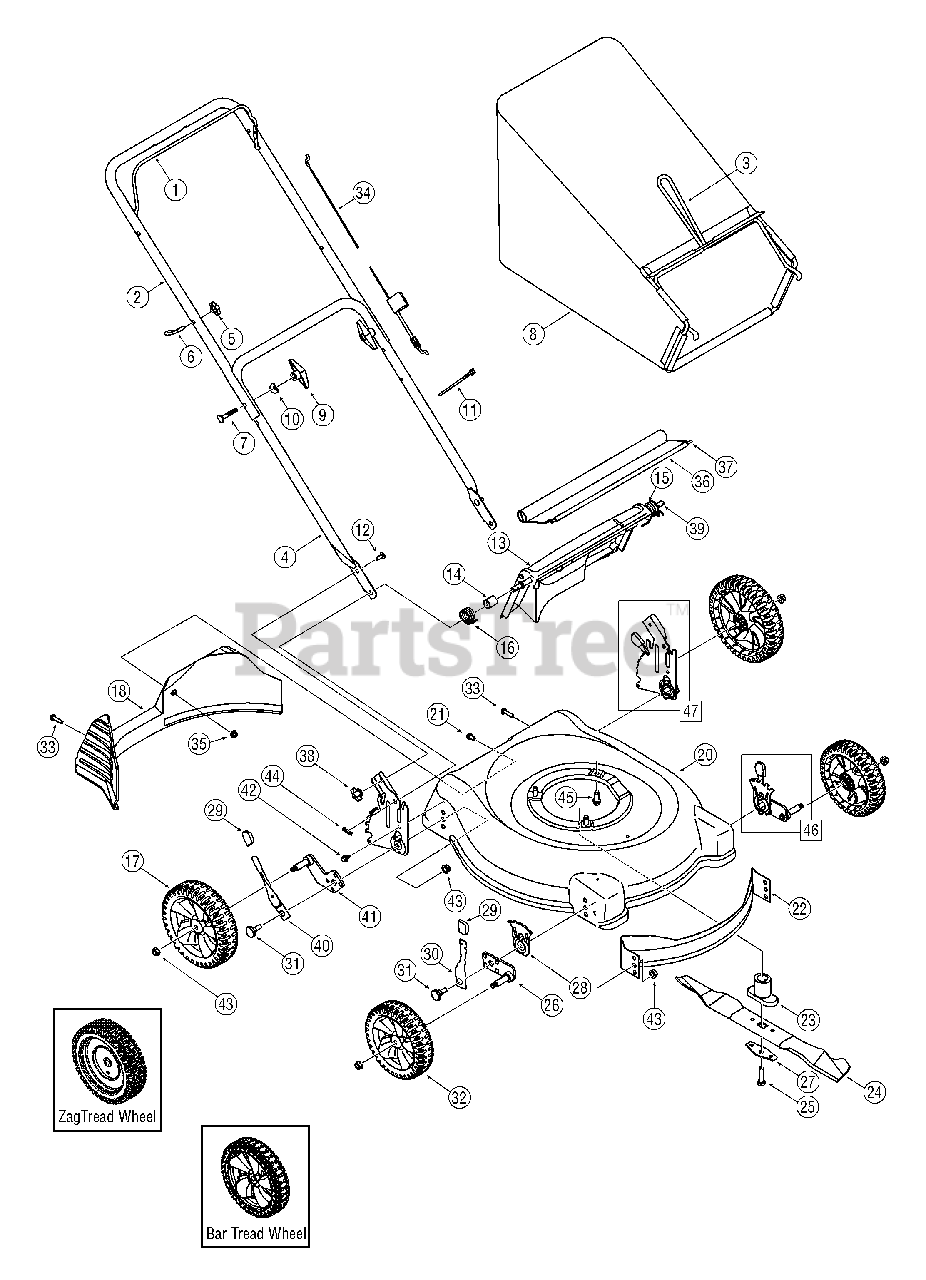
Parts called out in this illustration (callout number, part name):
5	Wing Nut
6	Rope Guide
7	Carriage Bolt ,5/16-18 x 2
8	Grass Bag Assembly
9	Hand Knob
10	Saddle Washer
11	Cable Tie
12	Carriage Bolt ,1/4-20
13	Rear Discharge Door
14	Spacer
15	Torsion Spring - LH
16	Torsion Spring - RH
17	Rear Wheel
18	Rear Baffle
19	Hubcap
22	Front Baffle
23	Blade Adapter
24	Mulching Blade
25	Hex Bolt
26	Pivot Arm Assembly - LH (7" wheel)
26	Pivot Arm Assembly -RH (7" wheel)
27	Blade Bell Support
28	Front Adjustment Plate
29	Adjustment Lever Knob
30	Spring Lever Assembly
31	Shoulder Screw
32	Front Wheel
33	Screw, 1/4-15 x 1.250
34	Control Cable - 37.25"
35	Flange Lock Nut, 1/4-20
36	Trailshield
37	Trailshield Wire
38	Wing Nut, 1/4-20
39	Rear Door Pivot Rod
40	Spring Lever
41	Pivot Arm Assembly - RH
41	Pivot Arm Assembly - LH
42	AB Screw
43	Flange Lock Nut, 3/8-16
44	Hairpin Clip
45	TT Sems Screw, 3/8-16 x 1.0
46	Ht. Adj. Assy. Front - RH (7" Wheel)
46	Ht. Adj. Assy. Front - LH (7" Wheel)
47	Rear Handle Bracket Assy. - LH
47	Rear Handle Bracket Assy. - RH
